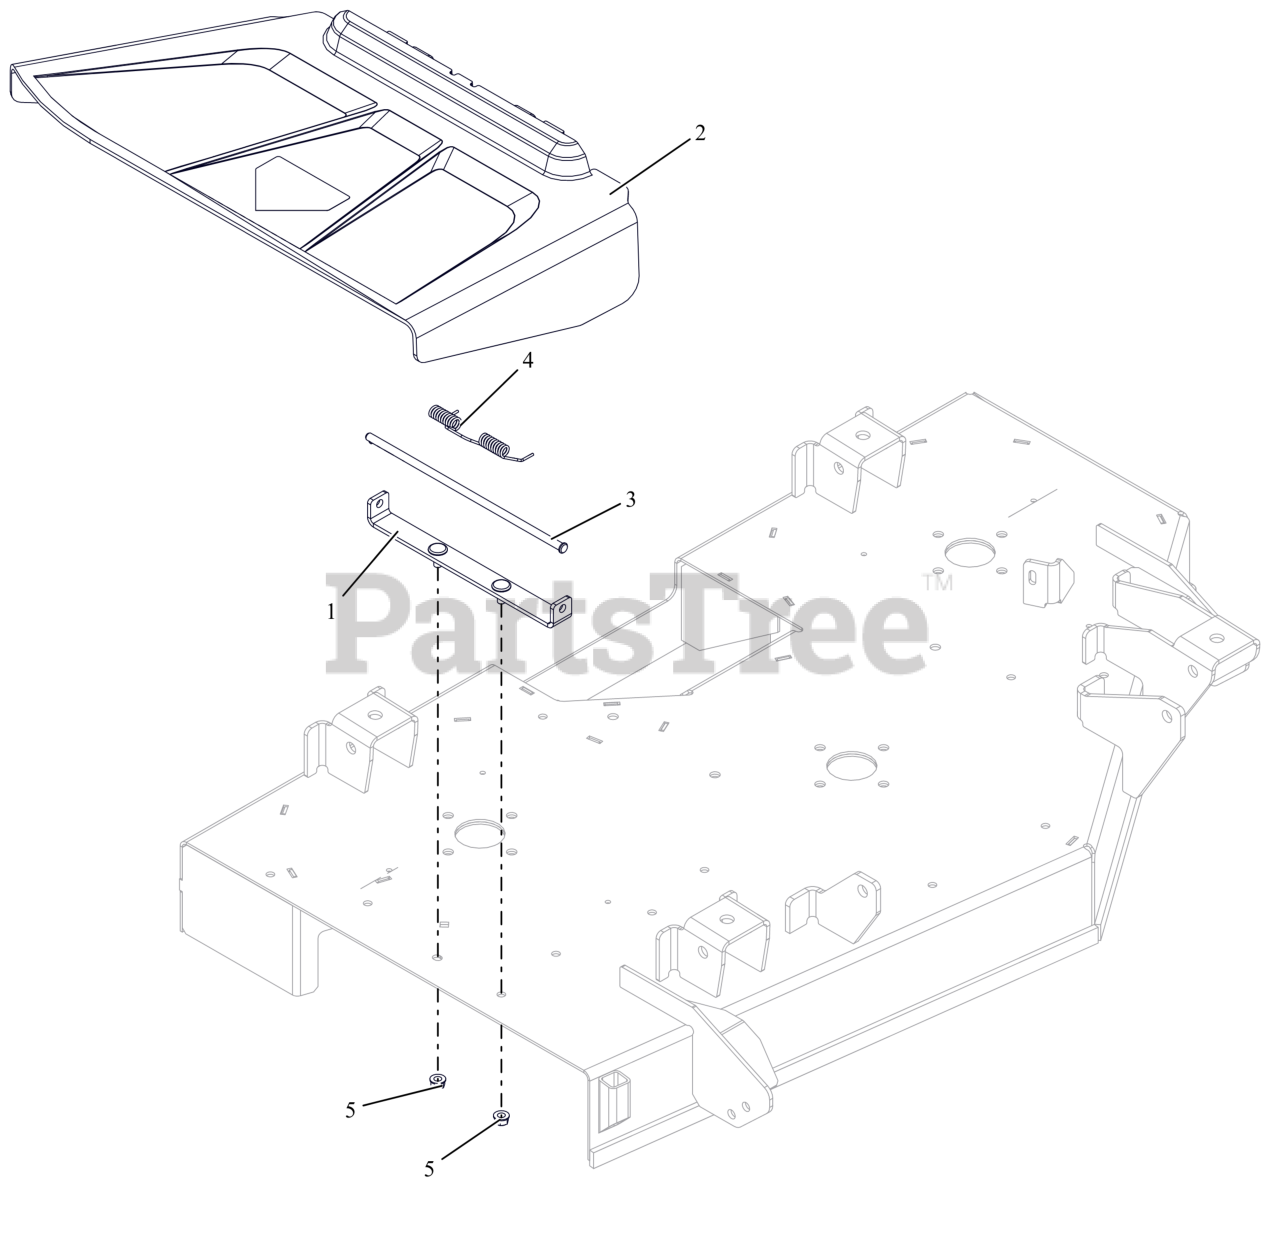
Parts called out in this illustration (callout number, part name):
2	CHUTE, SIDE DISCHARGE
3	PIN, SLIC-.312X10.45
4	SPRING-TORSION
5	NUT-LK-TOP-FLG .312-18 GF ZCC
